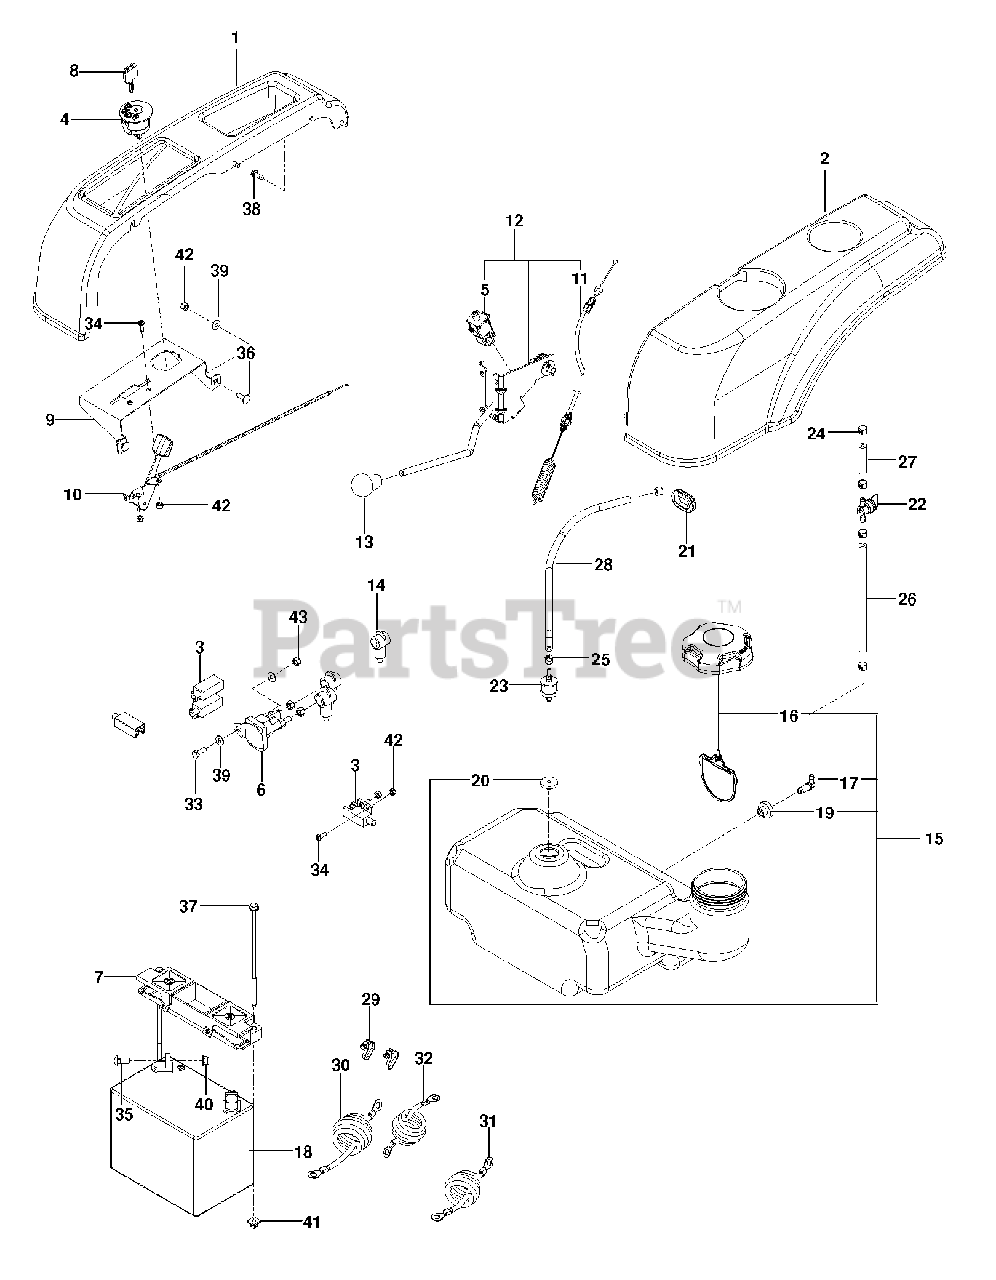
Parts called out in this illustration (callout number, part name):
1	FENDER RH
2	FENDER LH
4	IGNITION SWITCH
5	SWITCH INTERLOOK PUSH-IN
6	SOLENOID.W/BRASS.PLUNG
7	BATTERY HOLD DOWN
9	CONTROL PANEL MT.
10	THROTTLE CABLE
11	CABLE.CLUTCH.38".SERVICE
12	ASM, CLUTCH ENGAGE W/CABLE
13	KNOB - SHIFT
14	TERMINAL COVER-SM
15	FUEL TANK ASM SMALL
16	CAP, FUEL
19	RUBBER GROMMET
20	GROMMET, CHECK VALVE
22	FUEL VALVE
23	VALVE.FUEL.CHECK
24	HOSE CLAMP
25	CLAMP, HOSE
26	HOSE 1/4 X 8
27	HOSE 1/4 X 2"
28	HOSE, FUEL, 3/16" X 20"
29	TIE WRAP, 8-3/8", W/CLIP
30	POST.CABLE LONG
31	CABLE POSITIVE, LONG
32	BATTERY CABLE, NEGATIVE
34	SCREW #10-24 X 5/8
35	BOLT 5/16C X 3/4" CARRIAGE
36	RHSNB 1/4C X 3/4
38	SCREW 1/4 X 5/8
39	WASHER 1/4 SAE
40	5/16-18 NYLOC FLANGE NUT
41	PUSH NUT-NYLON
42	NUT 10-24 NYLOC
43	LOCKNUT
